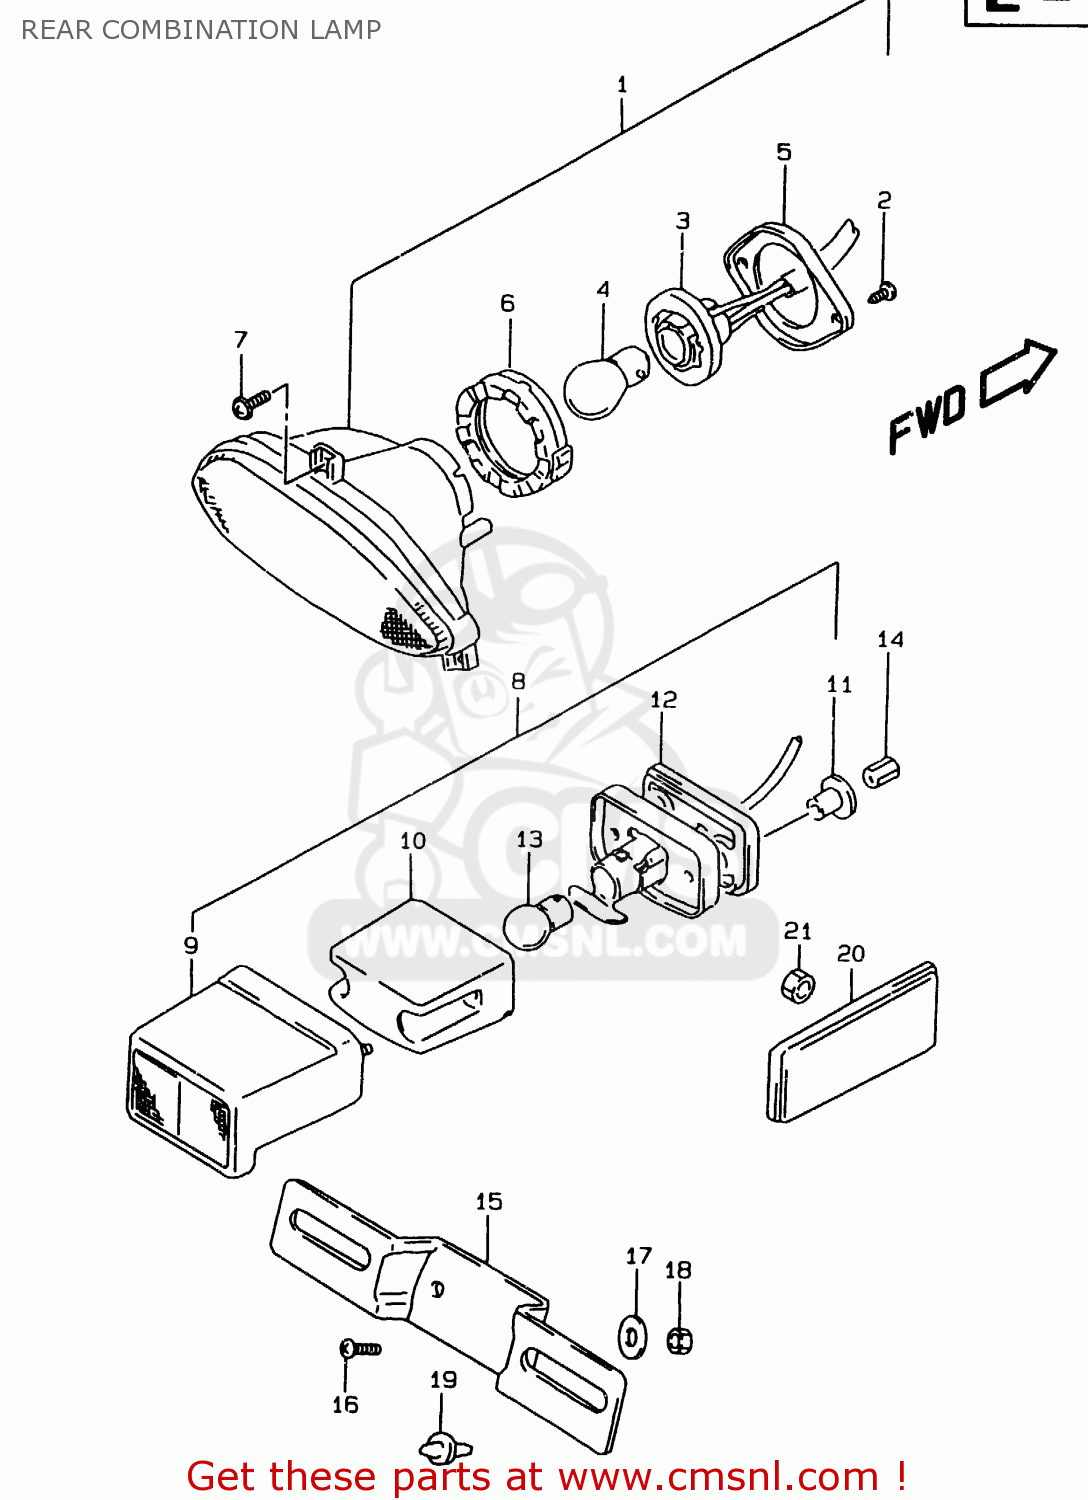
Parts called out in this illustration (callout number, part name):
1	LAMP ASSY,RR COMBINATION
2	SCREW
3	SOCKET & CORD
4	BULB(12V21/5W)
5	PLATE NO.2
6	CUSHION
7	TPG SCREW
8	LAMP ASSY,LICENSE PLATE
9	COVER,LENS
10	LENS
11	SPACER
12	CUSHION
13	BULB(12V5W,BF150-40160A)
14	NUT
15	BRACKET,LICENSE PLATE
16	SCREW 6X12
17	WASHER(6.5X20X1.6)
18	NUT 6MM
19	CUSHION
20	REFLEX REFLECTOR,FR SIDE
21	NUT
